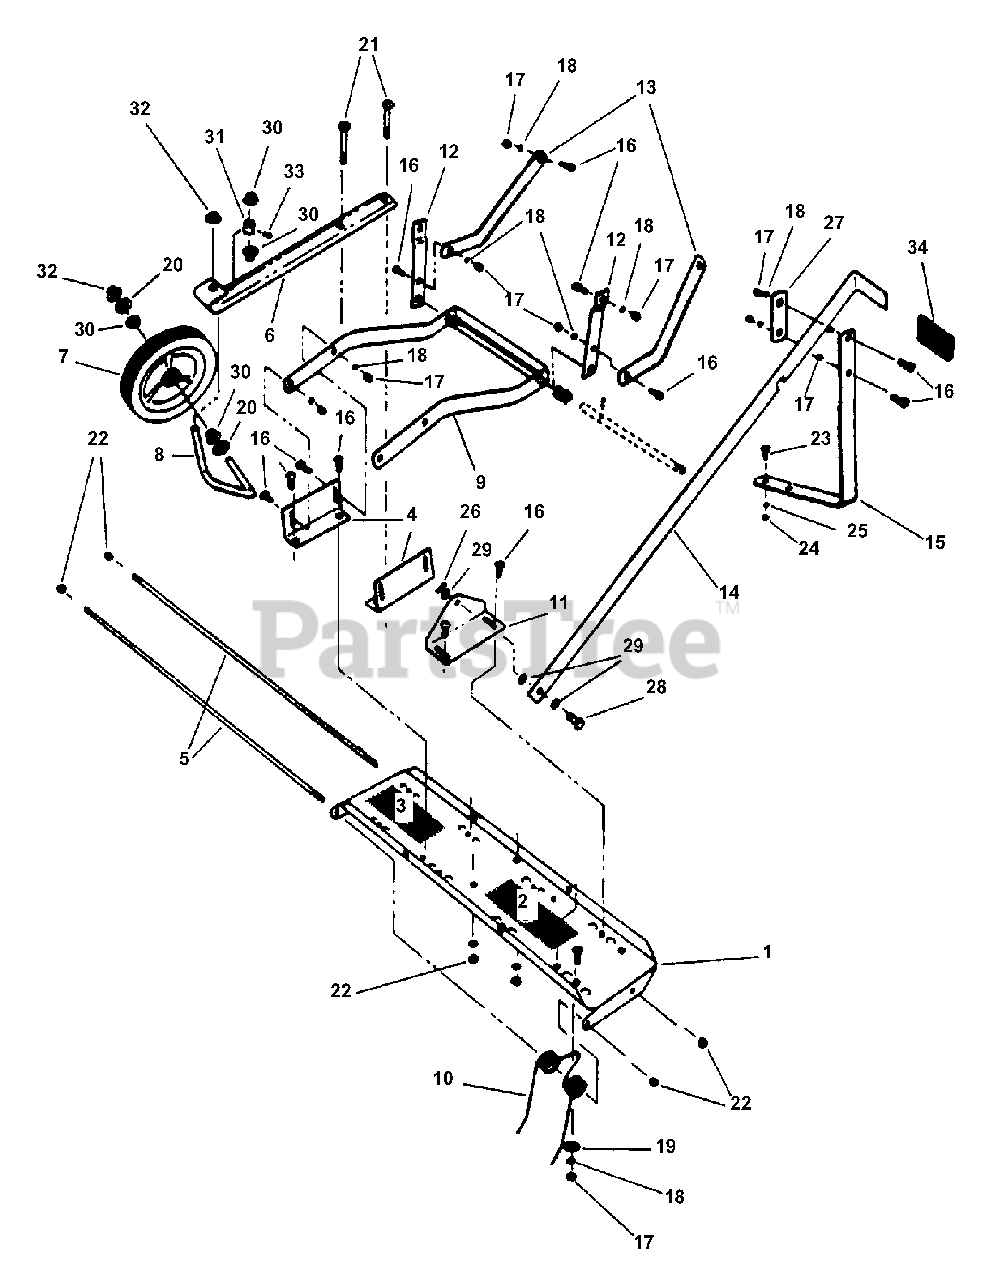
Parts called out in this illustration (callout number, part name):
1	TRAY, Tine
2	DECAL, Adjustment
3	DECAL, Thatcherizer
4	BRACKET, Frame Mounting
5	ROD, Tine
6	SUPPORT, Wheel
7	WHEEL, 7 x 1.50 V21
8	AXLE, Wheel
9	ASSEMBLY, Mounting Bracket Mechanism
10	TINE, Thatching
11	BRACKET, Lift
12	BAR, Thatcher Mount
13	BAR, Mount Brace
14	HANDLE, Lift
15	BRACKET, Lift Lock
16	BOLT, 5/16-18 x 1" Short Neck Carriage, Grade 5
17	NUT, 5/16-18 Hex
18	WASHER, 5/16" Split Lock
19	WASHER, 5/16" Flat
20	WASHER, 1/2" SAE Flat
21	BOLT, 1/4-20 x 1-3/4" Square Neck Carriage, Grade 2
22	NUT, 1/4-20 Hex Top Lock
23	SCREW, 3/8-16 x 1" Hex Head Cap, Grade 5
24	NUT, 3/8-16 Hex
25	WASHER, 3/8 Split Lock
26	PIN, Hair
27	STRAP, Handle Retaining
28	PIN, Clevis
29	WASHER, 5/16" Flat
30	BEARING, Nylon
31	BUSHING, Wheel Adjustment
32	NUT, 1/2" Push
33	SCREW, 5/16-18 x 1/4" Set
34	GRIP, Vinyl
